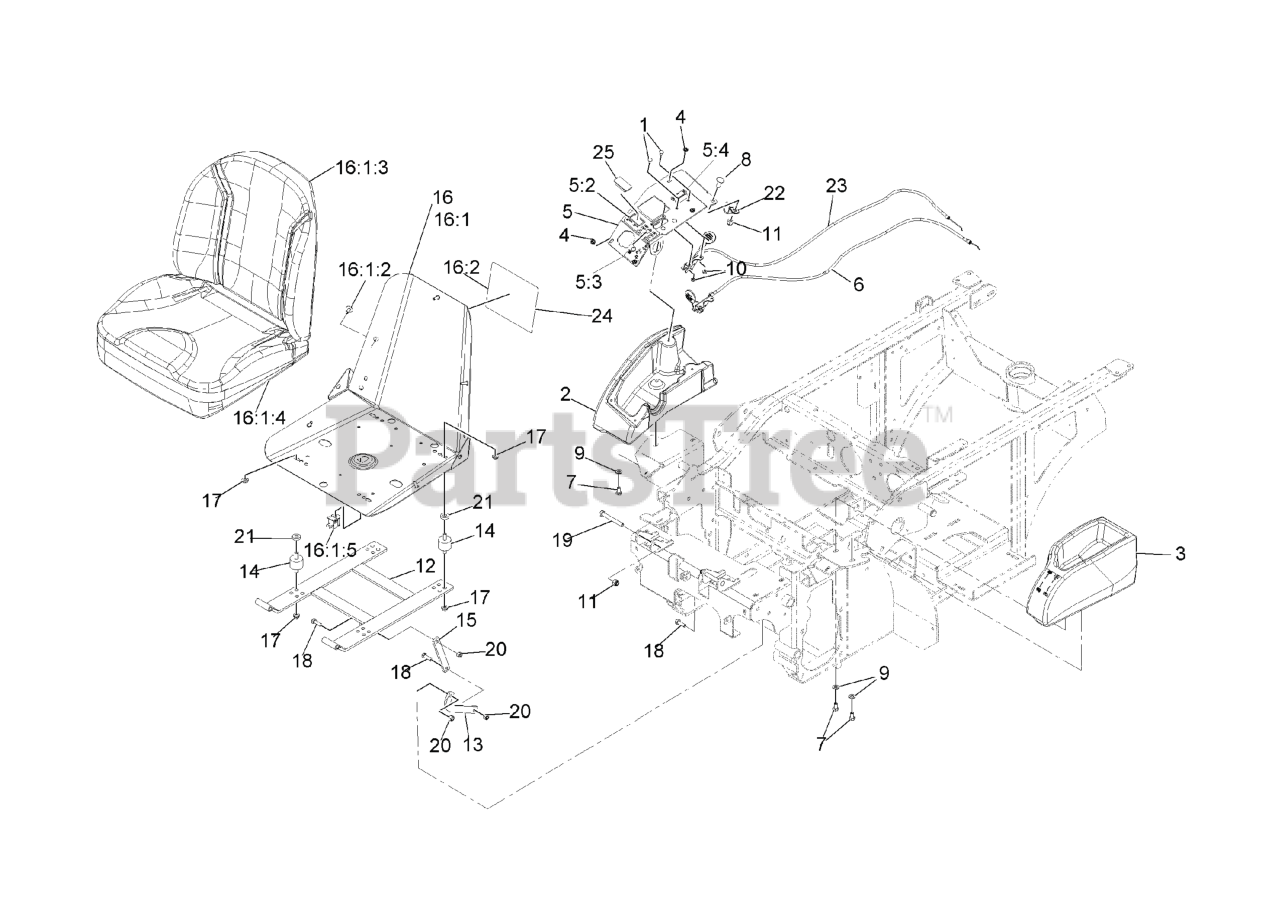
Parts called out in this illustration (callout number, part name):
1	BOLT-CARR
2	CONSOLE-RH
3	CONSOLE, LH GREY
4	SCREW-PPH
5	CONTROL PANEL ASM
5:2	Decal-Nav Console 640Kc
5:3	DECAL-SPEED CONTROL
5:4	DECAL-CHOKE
6	CABLE-THROTTLE
7	SCREW-HH
8	SCREW-CARR
9	WASHER-PLAIN
10	NUT-LOCK, NI
11	NUT-LOCK, NI
12	FRAME-SEAT
13	LINK-SEAT STOP
14	MOUNT-VIBRATION, RUBBER
15	LINK-SEAT
16	ASM-SEAT W/DECAL
16:1	ASM-Seat, Navigator
16:1:2	BOLT-SEAT
16:1:3	CUSHION-SEAT, BACK
16:1:4	COVER-SEAT BOTTOM SVC
16:1:5	SWITCH-BAIL
16:2	Decal-Service Aid
18	SCREW-HH
19	SCREW-HH
20	NUT-LOCK, NI
21	SPACER
22	CLIP-LOOM
23	CABLE-CHOKE
24	Decal-Service Aid
25	PLUG-HOLE
